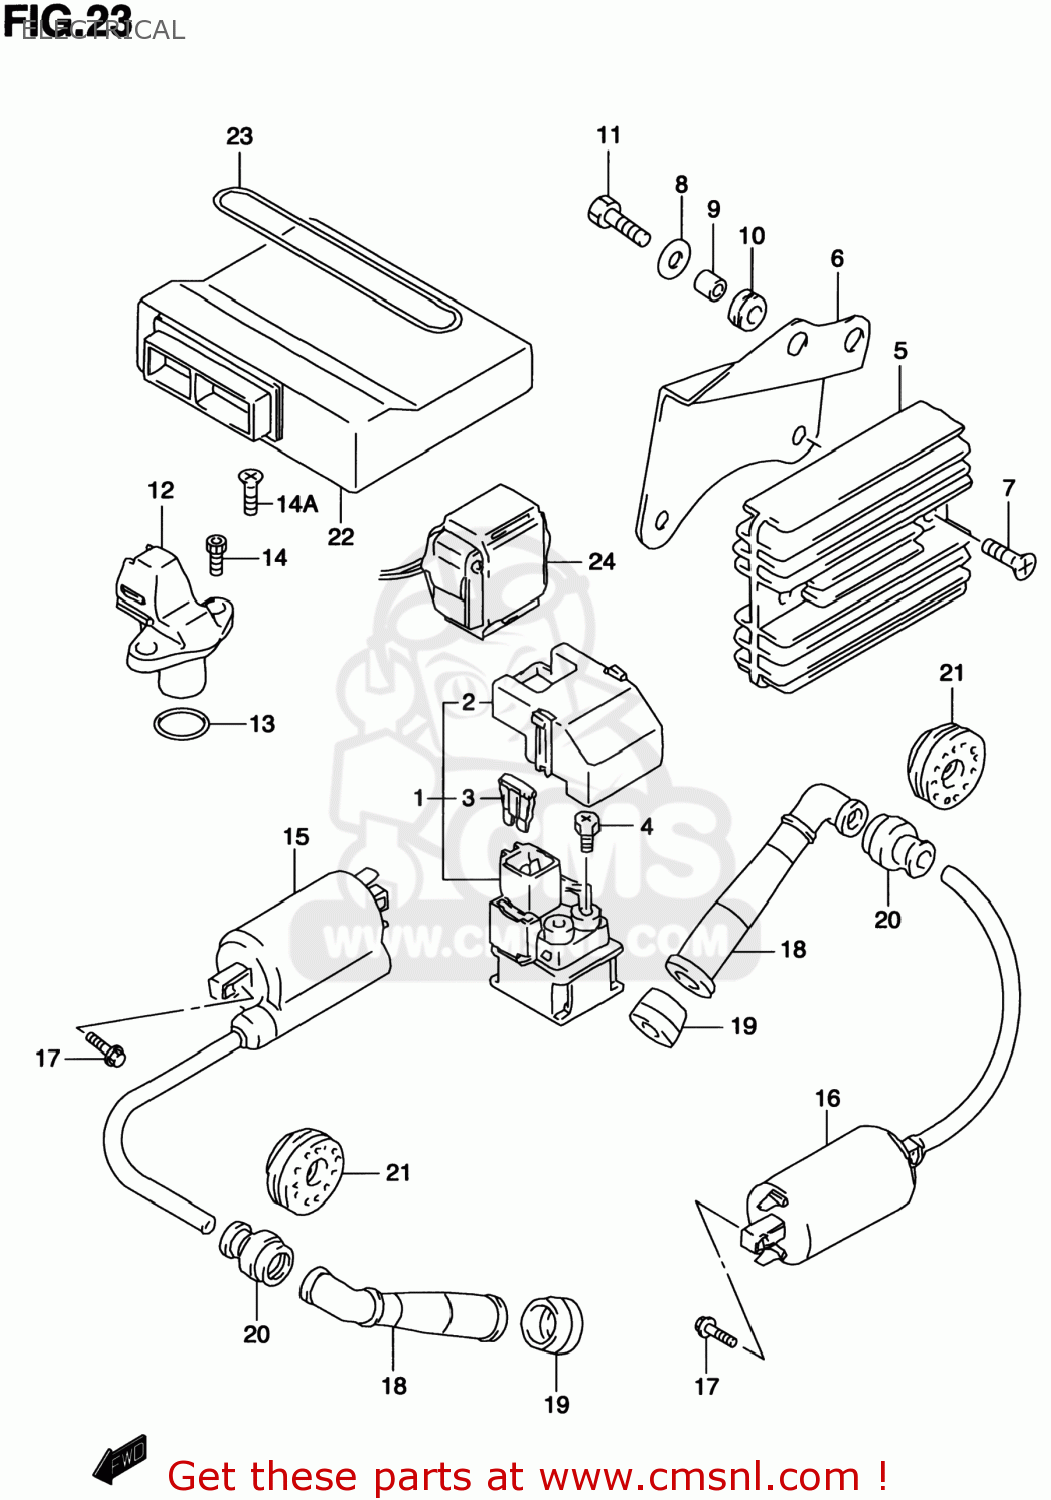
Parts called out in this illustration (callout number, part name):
1	RELAY ASSY,STARTING MOTOR
2	COVER,RELAY ASSEMBLY
3	FUSE(30A)
4	SCREW(6X8)
5	RECTIFIER ASSY
6	BRACKET,RECT FTG
7	SCREW (6X20)
8	WASHER(6.5X18X1.6)
9	SPACER(6.5X9X6.7)
10	CUSHION
11	BOLT
12	SENSOR ASSY,CAM POSITION
13	PACKING (NAS)
14	BOLT,OIL FILLE
14A	SCREW 6X16
15	COIL ASSY,IGNITION
16	COIL ASSY,IGNITION
17	SCREW, PRESSURE SENSOR
18	CAP,SPARK PLUG
19	SEAL,SPARK PLUG CAP
20	SEAL,HIGH TENSION CORD
21	COVER,SPARK PLUG CAP
22	CONTROL UNIT,EPI
23	BAND,BATTERY
24	SENSOR ASSY,FUEL CUT
